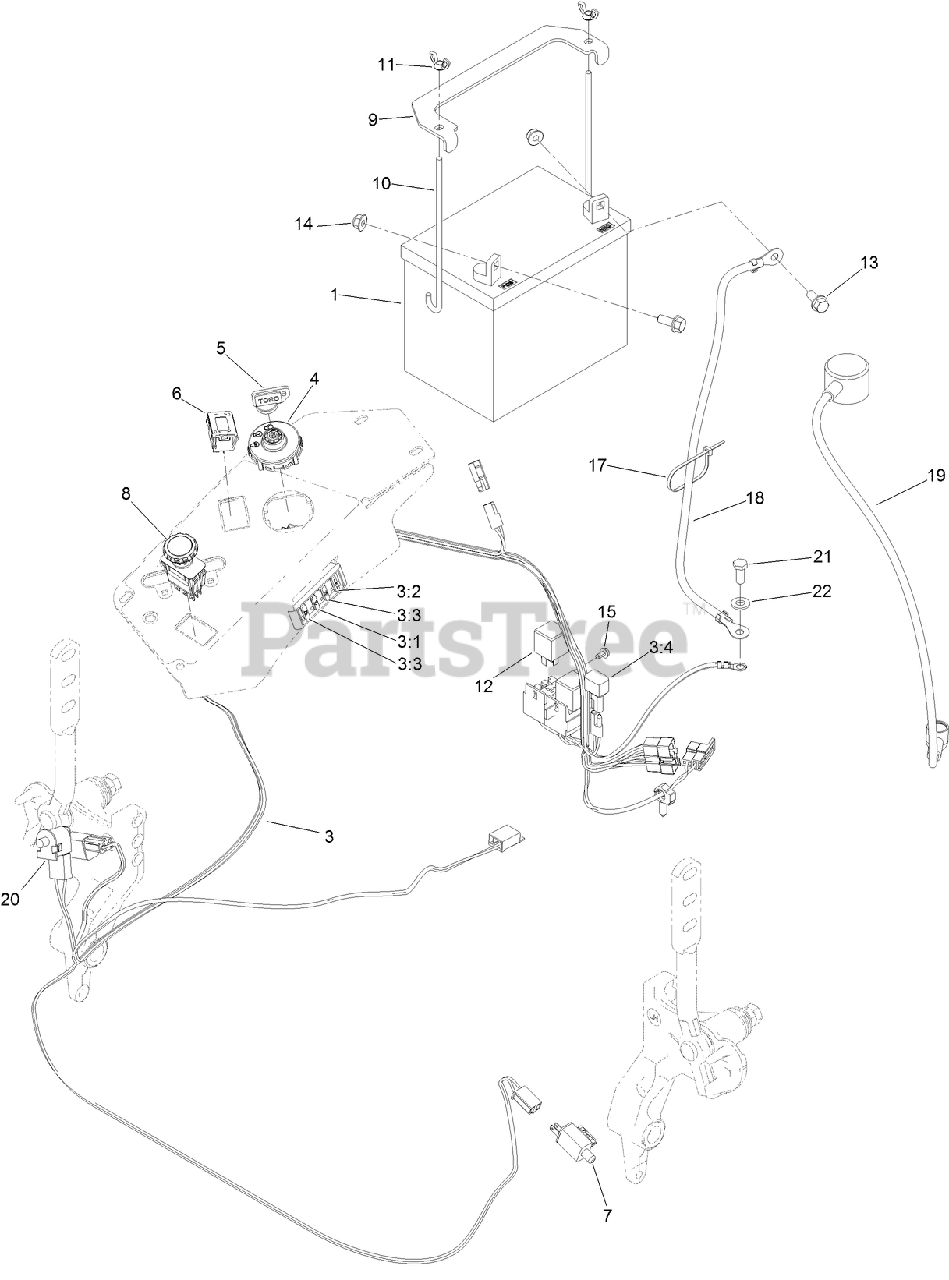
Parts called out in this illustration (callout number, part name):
1	BATTERY-DRY
3	HARNESS-WIRE
3:1	FUSE-BLADE, 10 AMP
3:2	FUSE-BLADE, 15 AMP
3:3	FUSE-BLADE, 25 AMP
3:4	CAP-PLUG
4	SWITCH-IGNITION
5	KEY-IGNITION
6	HOURMETER
7	SWITCH
8	SWITCH-PTO, 10 AMP
9	STRAP-TIE DOWN, BATTERY
10	BOLT-HOLDDOWN
11	WINGNUT
13	SCREW-HHF
14	NUT-HF, NI
15	SCREW-HWH
17	TIE-CABLE
18	CABLE-BATTERY, NEGATIVE
19	CABLE-BATTERY, POSITIVE
20	SWITCH-BAIL
21	SCREW-HH
22	WASHER-PLAIN
